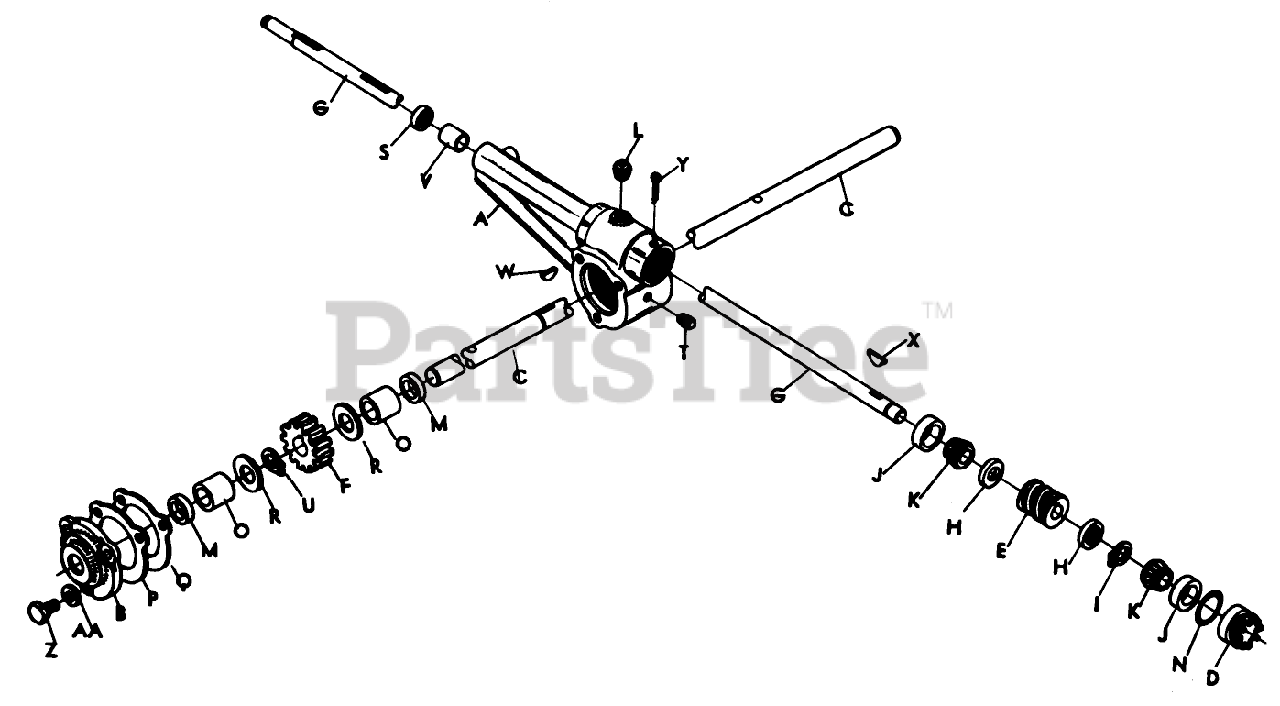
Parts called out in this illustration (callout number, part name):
A	Gear Case
W	1/4 x 7/8 Woodruff Key, Alloy H.T.
X	3/16 X 5/8 Hypro Key
Y	1/8 x 3/4 Cotter Pin, Pl.
Z	5/16-18 X 1 Hex. Hd. Cap Screw, H.T.
AA	5/16 Lock Washer,
